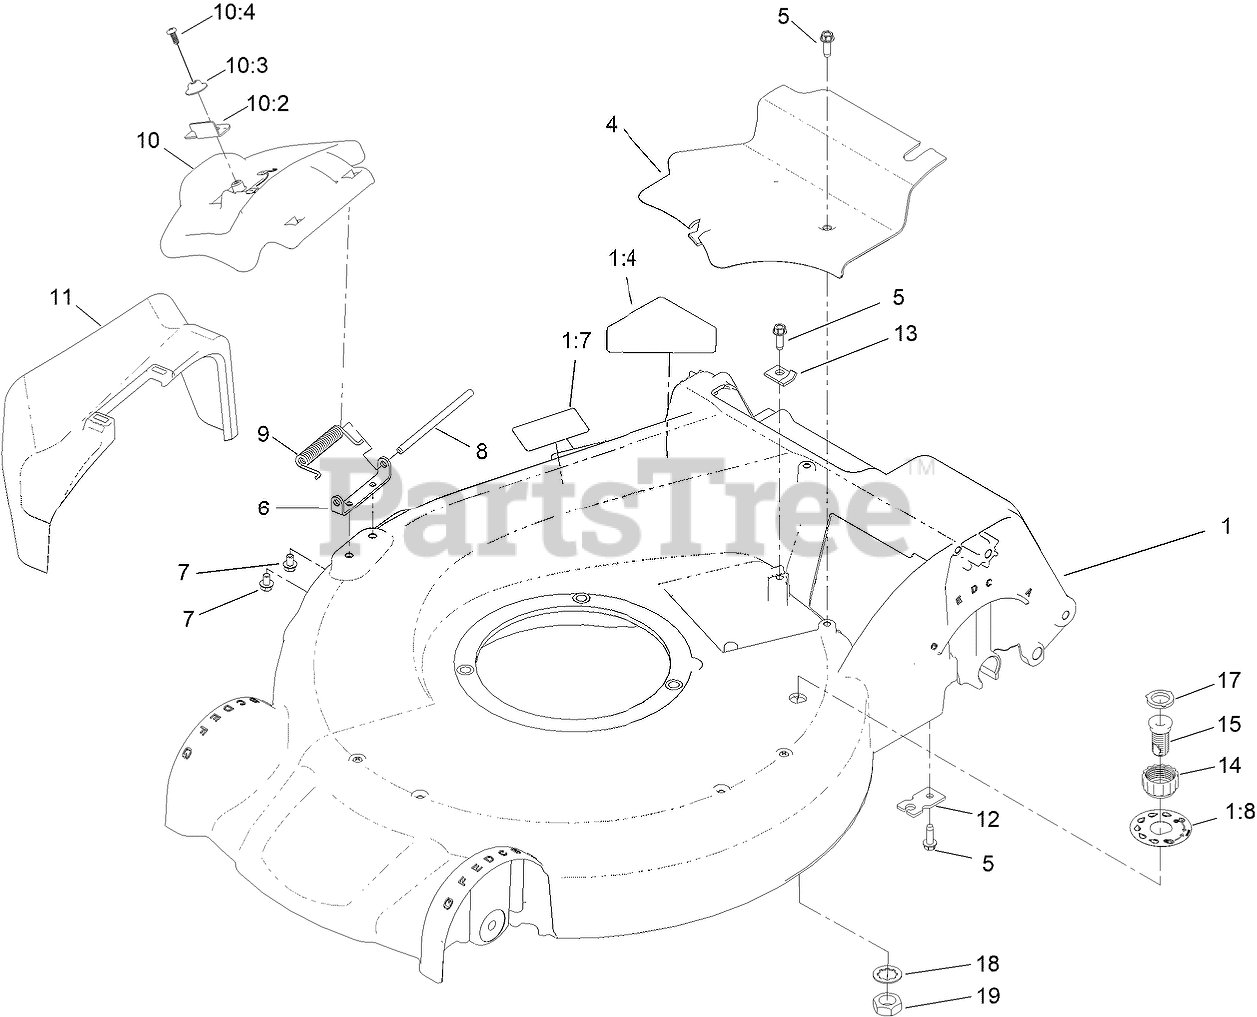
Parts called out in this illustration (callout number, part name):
1	HOUSING ASM
1:4	DECAL-DANGER
1:7	DECAL-PLACEMENT, FOOT
1:8	DECAL-QUICK WASH
4	COVER-BELT
5	SCREW-HWHTF
6	BRACKET-COVER
9	SPRING-TORSION
10	DISCHARGE DOOR ASM
10:2	LATCH-DOOR
10:3	CAP-DOOR
10:4	SCREW-PPH
11	CHUTE-DISCHARGE, SIDE
12	BRACKET-CABLE, TRACTION
13	CLAMP-CABLE
14	COUPLING-HOSE, WASHOUT PORT
15	PORT-WASHOUT
17	WASHER-SEAL, WASHOUT PORT
18	WASHER-LOCK
19	NUT-JAM
